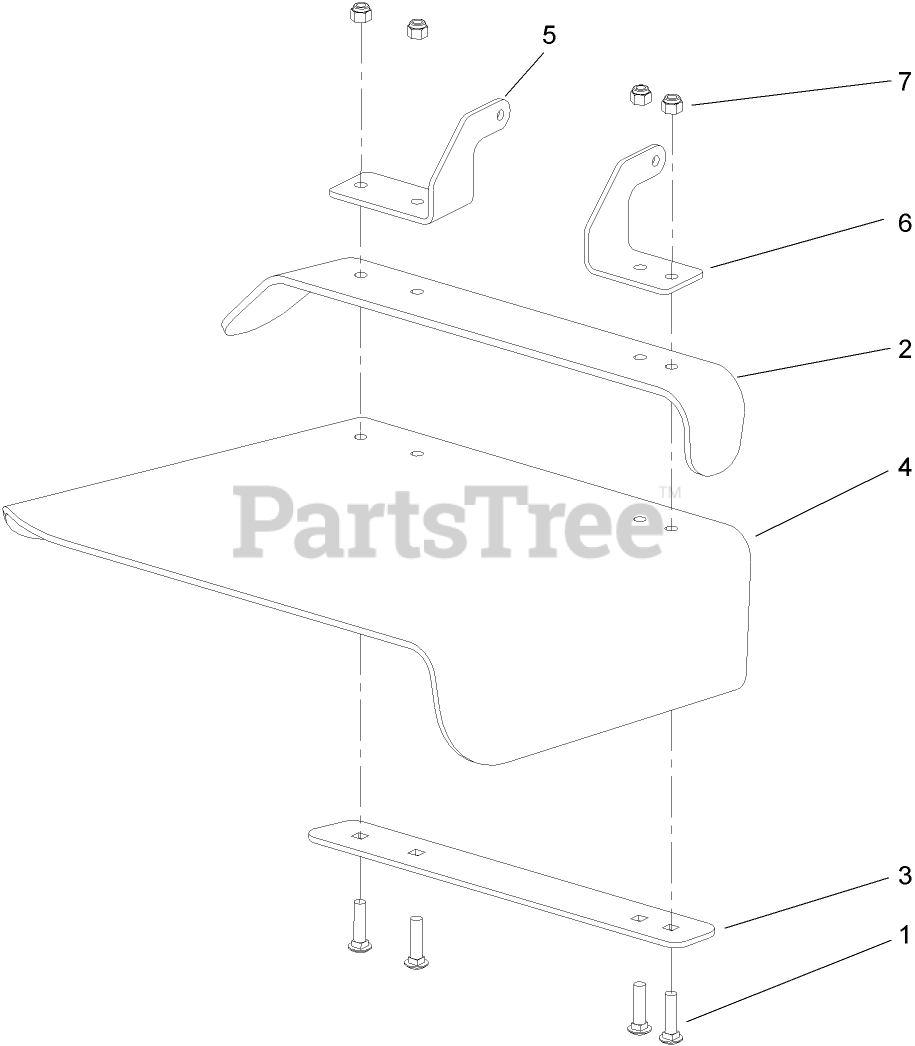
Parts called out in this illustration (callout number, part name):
1	SCREW-CARR
2	DEFLECTOR
3	STRAP-DISCHARGE
4	DEFLECTOR-RUBBER
5	BRACKET-HINGE, REAR
6	BRACKET-HINGE, FRONT
7	NUT-LOCK, NI
